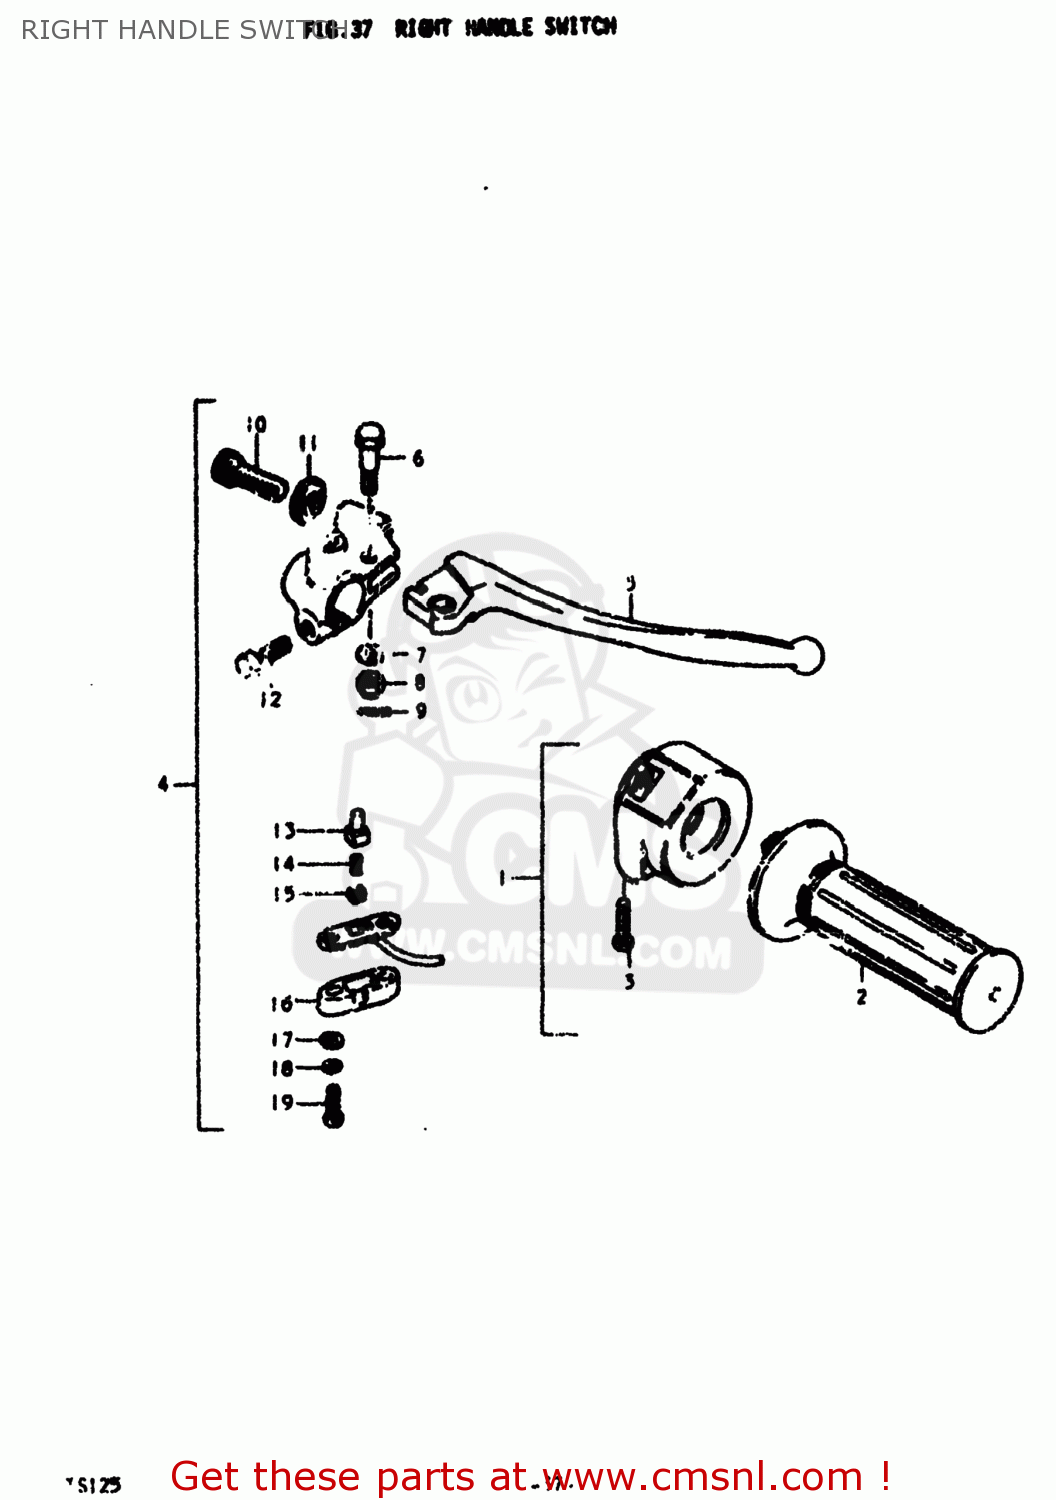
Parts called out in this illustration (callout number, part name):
1	GRIP ASSEMBLY,THROTTLE
2	GRIP,THROTTLE
3	SCREW
4	LEVER/SWITCH ASSEMBLY,BRAKE
5	LEVER,BRAKE
6	BOLT,LEVER
7	LOCK WASHER
8	NUT 6MM
9	COTTER PIN
10	ADJUSTER,CABLE
11	NUT,CABLE ADJUSTER
12	BOLT
13	HOLDER
14	SPRING
15	PLATE
16	COVER,FR BK TERMINAL BASE
17	WASHER
18	LOCK WASHER
19	SCREW
